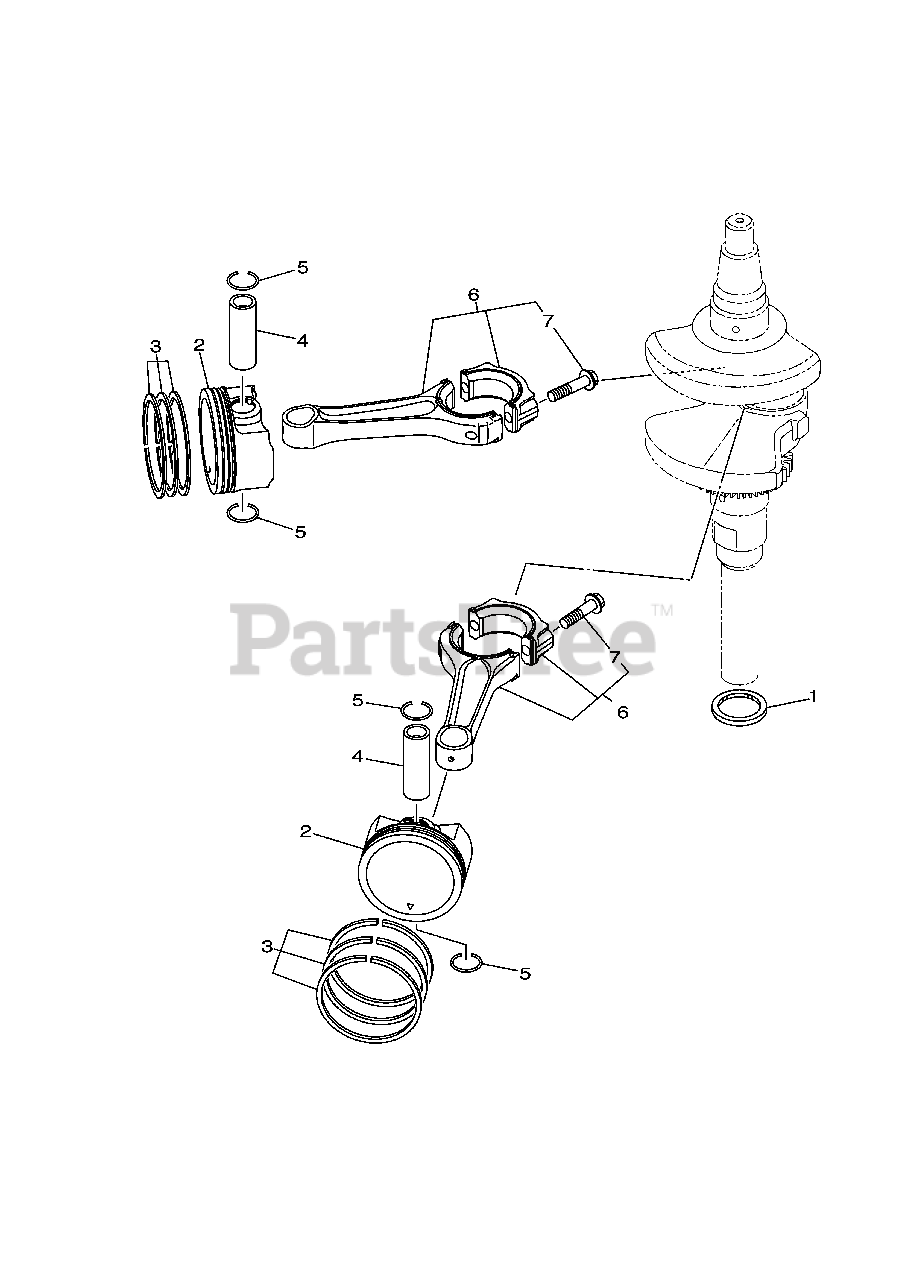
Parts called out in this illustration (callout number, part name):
2	PISTON
3	PISTON RING SET
4	PIN, PISTON
6	CONNECTING ROD ASSY
7	BOLT, CONNECTING ROD
